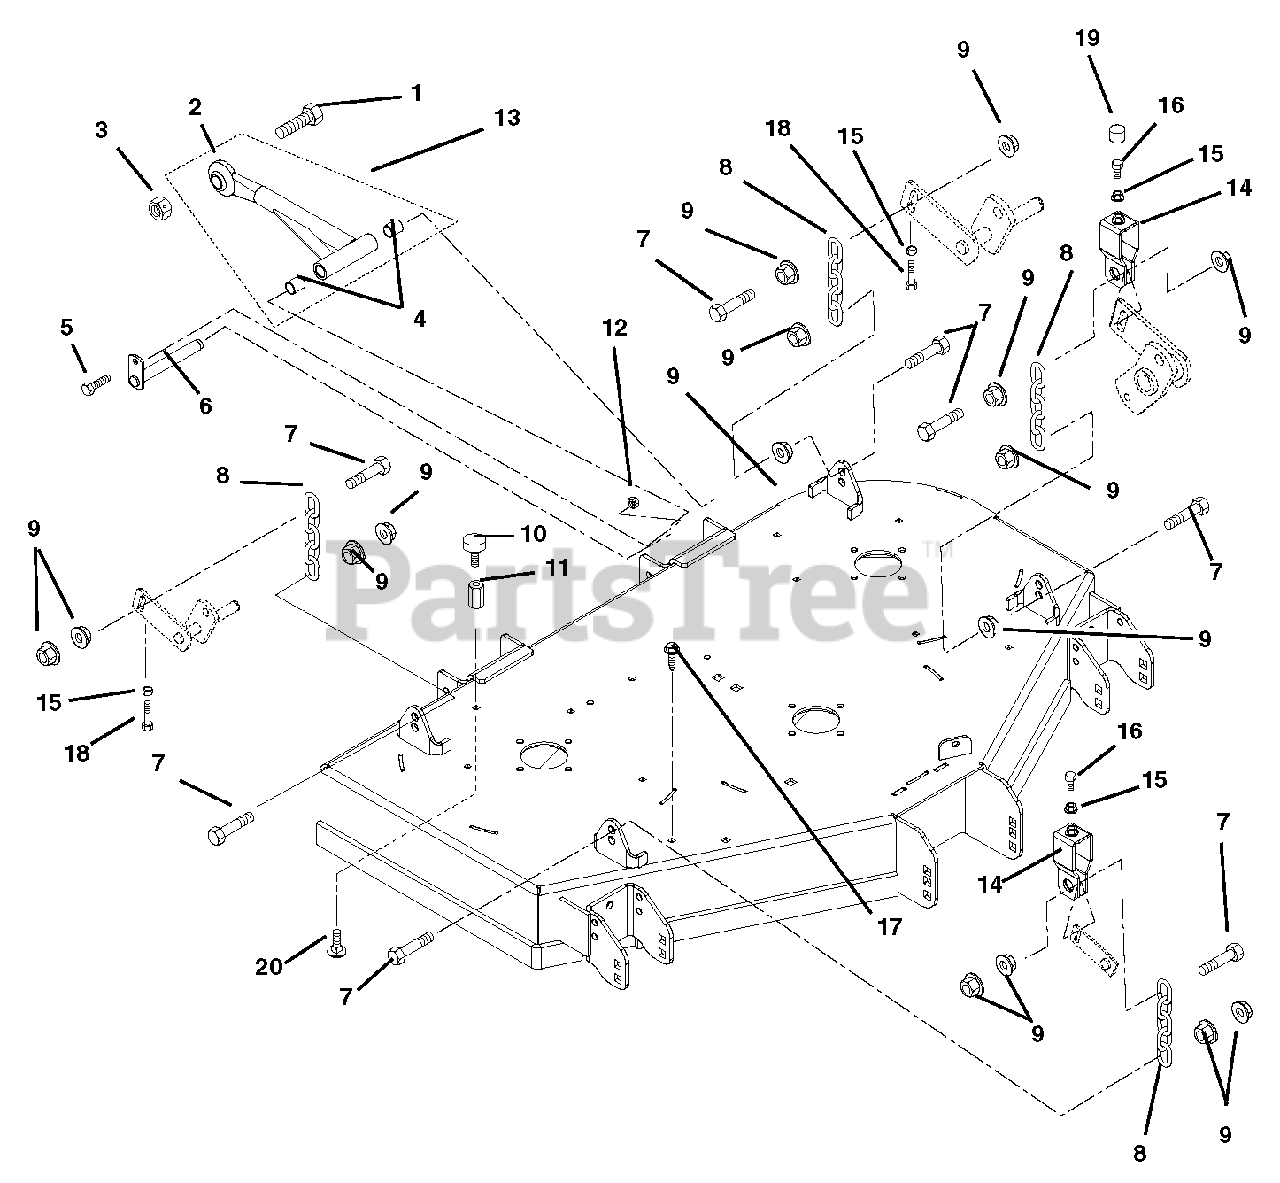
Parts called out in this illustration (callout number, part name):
1	Bolt, Hex .875-9 x 2.75 Grade 5
2	Mower Mounting Arm Weldment
3	Nut, Locking Center .875-9
4	Bearing, .75 x .875 x 1.00
5	Bolt, Hex .38-16 x 1.00
6	Weldment, Mower Mounting Pin
7	Bolt, Hex M12-1.75 x 50 Grade 5
8	Chain, Link
9	Nut, Spin Lock Flange M12-1.75
10	Bumper, Rubber
11	Nut, Coupling, .31-18 x 3.00
12	Nut, .38-16 Nyloc Flange
13	Assembly, Mower Mounting Arm (Includes item # 2 and item # 4)
14	Bracket, Deck Leveling
15	Nut, Jam .312-18
16	Bolt, Hex .31-18 x 2.00 Full Thread
17	Screw, Tapping .38-16 x .50 Hex Washer Head Thread
18	Bolt, Hex .312-18 x 1.50 Grade 5
19	Cap, Vinyl .50 ID x 1.50LG x .055
20	Bolt, Round Head Square Neck, .31-18 x .75 Loc-Tite®
